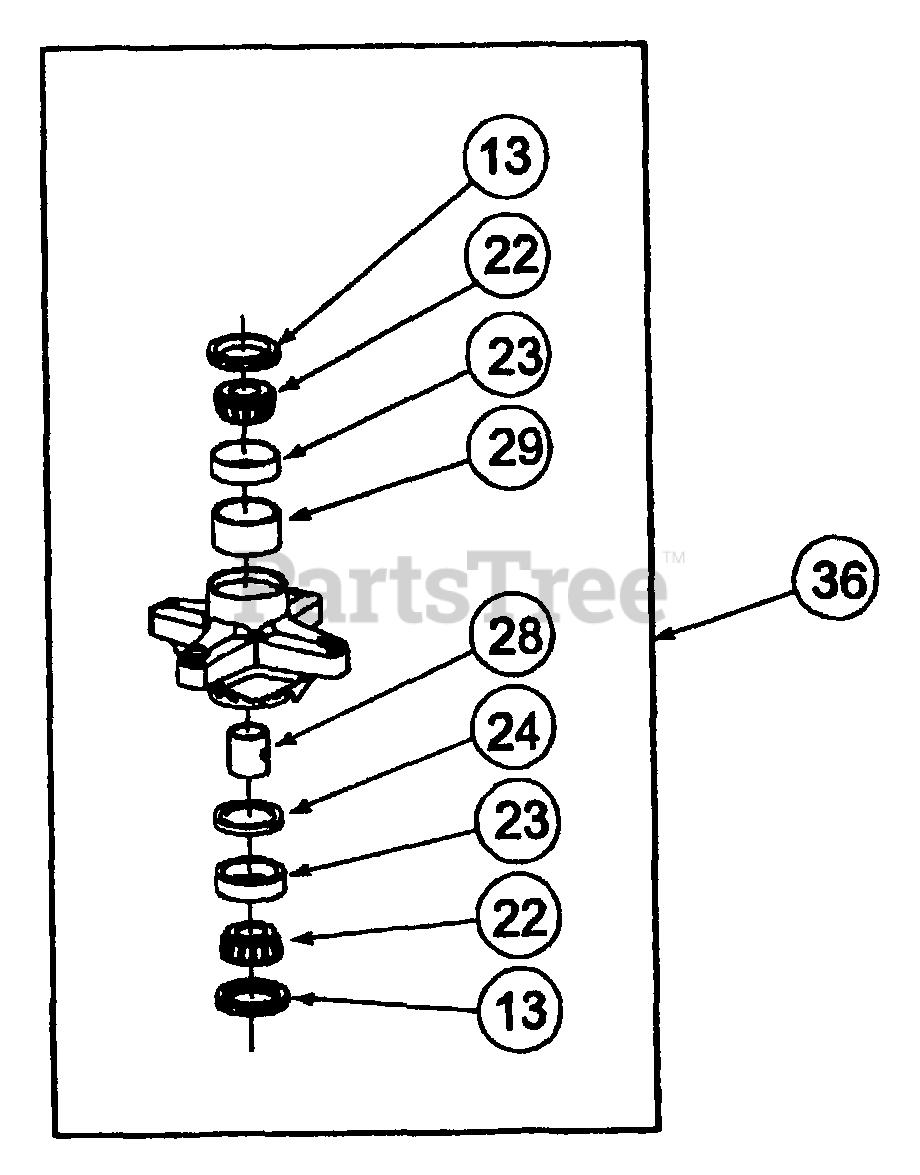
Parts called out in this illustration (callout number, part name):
13	Seal, Oil, 1.25 x 1.874 x .25
22	Cone, Bearing
23	Cup, Bearing
24	Spacer, Bearing
28	Spacer, Bearing, .780 x .963 x .7777
29	Spacer, Bearing, 1.615 x 1.86 x .8427
36	Spindle Assy
